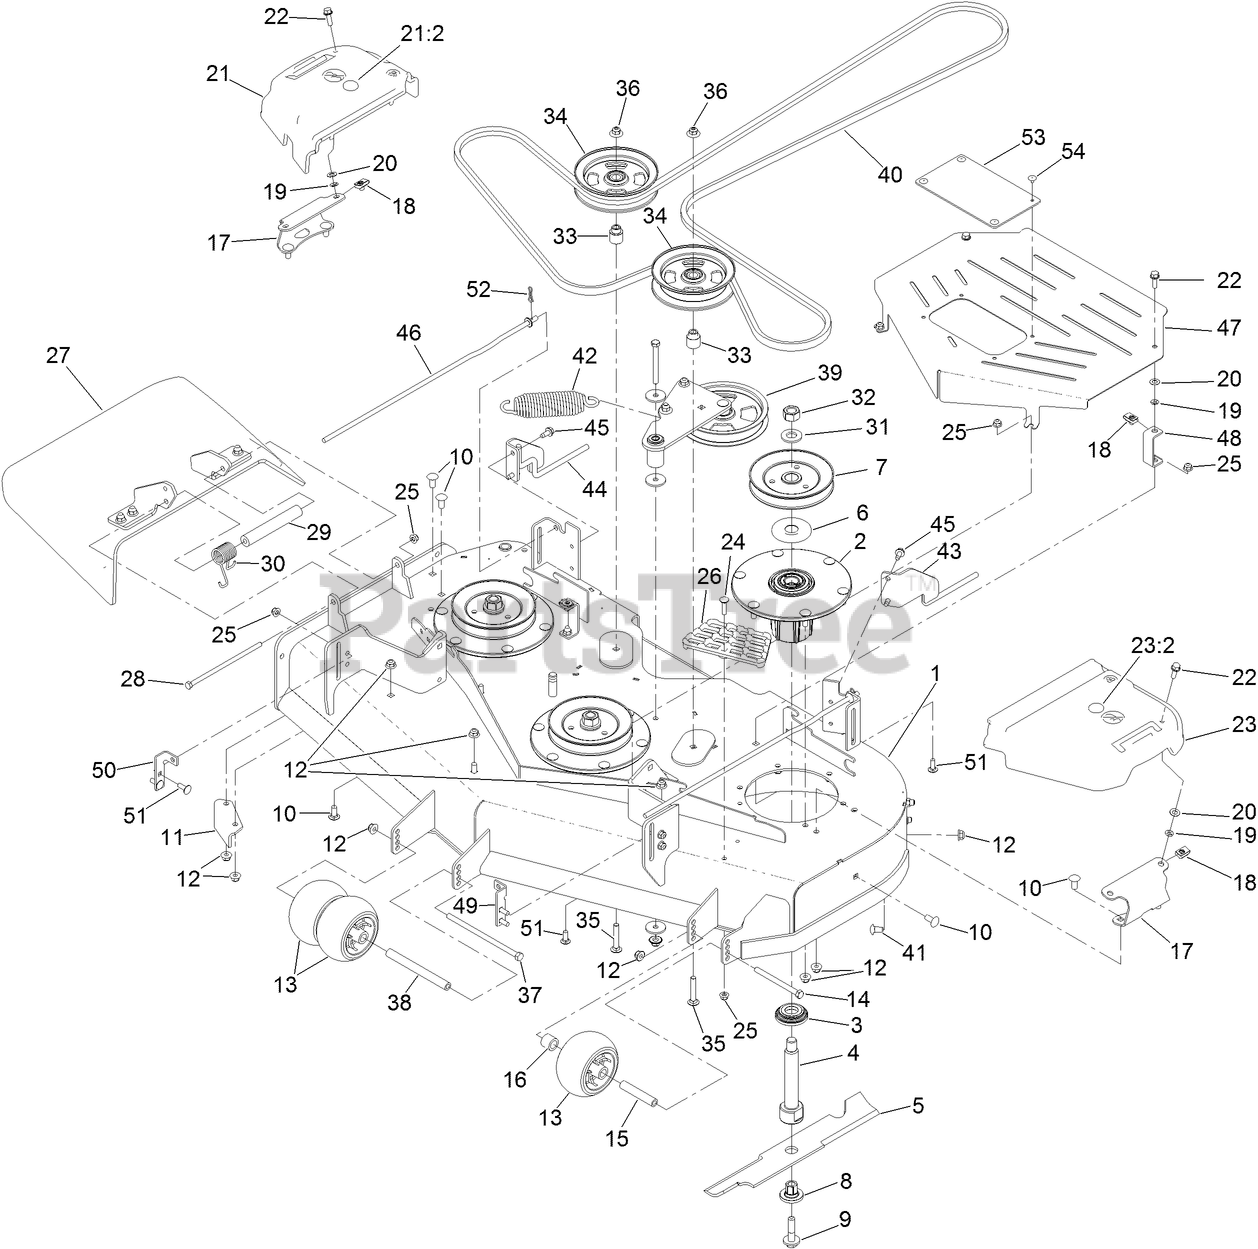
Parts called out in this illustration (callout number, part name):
1	DECK DECAL ASM
2	SPINDLE ASM
3	GUARD-BOTTOM
4	SHAFT-SPINDLE
5	BLADE-16.50 HIGH FLOW
6	GUARD-BEARING, TOP
7	SHEAVE,BLADE DRIVE 5.91
8	BUSHING-HEX
9	SCREW-SEMS
10	SCREW-CARR
11	BAFFLE-DISCHARGE
12	NUT-HF, NI
13	ROLLER-SCALP, ANTI
14	SCREW-HH
15	TUBE-SPANNER
16	TUBE-SPACER
17	BRACKET-COVER, BELT
18	NUT-U
19	NUT-PUSH
20	WASHER-THRUST
21	RH BELT COVER ASM
21:2	PLUG-PLASTIC
22	SCREW-HHF
23	LH BELT COVER ASM
23:2	PLUG-PLASTIC
24	SCREW-CARR
25	NUT-HF, NI
26	STEP-DECK
27	RUBBER DEFLECTOR ASM
28	SCREW-HH
29	SPACER
30	SPRING-TORSION
31	WASHER
32	NUT-HEX
33	BUSHING, IDLER
34	PULLEY-IDLER, FLAT
35	SCREW-CARR
36	NUT-FLANGE, NI
37	SCREW-HH
38	SPACER-WHEEL
39	IDLER ARM ASM
40	BELT-V
41	SCREW-CARR
42	SPRING-EXTENSION
43	SUPPORT-LOWER LH
44	SUPPORT-LOWER RH
45	SCREW-HWHTF
46	ROD-SKIRT, LOWER
47	GUARD-CENTER BELT 48
48	BRACKET-GUARD
49	BRACKET-SUPPORT, LH
50	BRACKET-SUPPORT, RH
51	BOLT-CARR
52	PIN-COTTER, LOCKING
53	SHIELD-RUBBER
54	RIVET-POP
